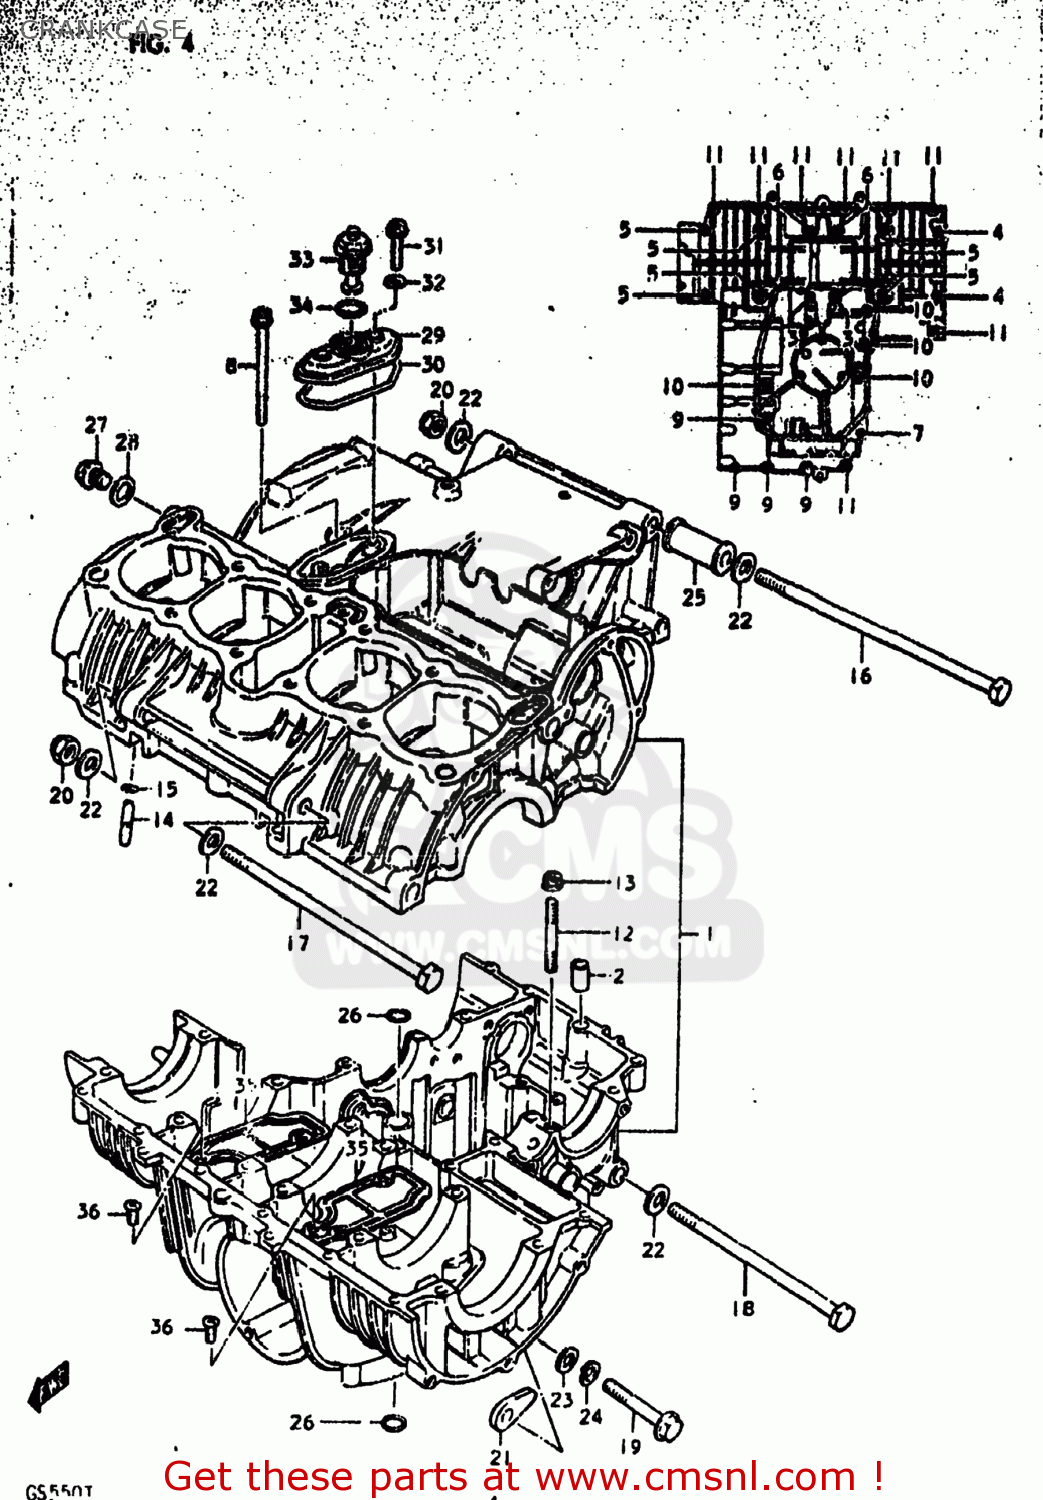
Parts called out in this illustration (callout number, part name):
1	CRANKCASE SET
2	PIN
3	BOLT
4	BOLT 8X90
5	BOLT (8X70)
6	BOLT 8X55
7	BOLT (8X45)
8	BOLT (6X90)
9	BOLT (6X60)
10	BOLT ,6X50
11	BOLT
12	STUD BOLT
13	NUT
14	UNION
15	O-RING
16	BOLT 10X270
17	BOLT
18	BOLT(10X165)
19	BOLT 10X55
20	NUT
21	NUT
22	WASHER
23	WASHER(10.5X20X3.2)
24	LOCK WASHER
25	SPACER,ENGINE MOUNT
26	O RING(D:3.2,ID:12.9)
27	PLUG (14X12)
28	GASKET(14X19.2X2) (NAS)
29	HOUSING,OIL PRESSURE SWITCH
30	O RING,PRESSURE SWITCH HOUSING
31	BOLT
32	GASKET (NAS)
33	SWITCH ASSEMBLY
34	O RING(D:1.9,ID:18.8)
35	PLATE,OIL SEPARATOR
36	SCREW
